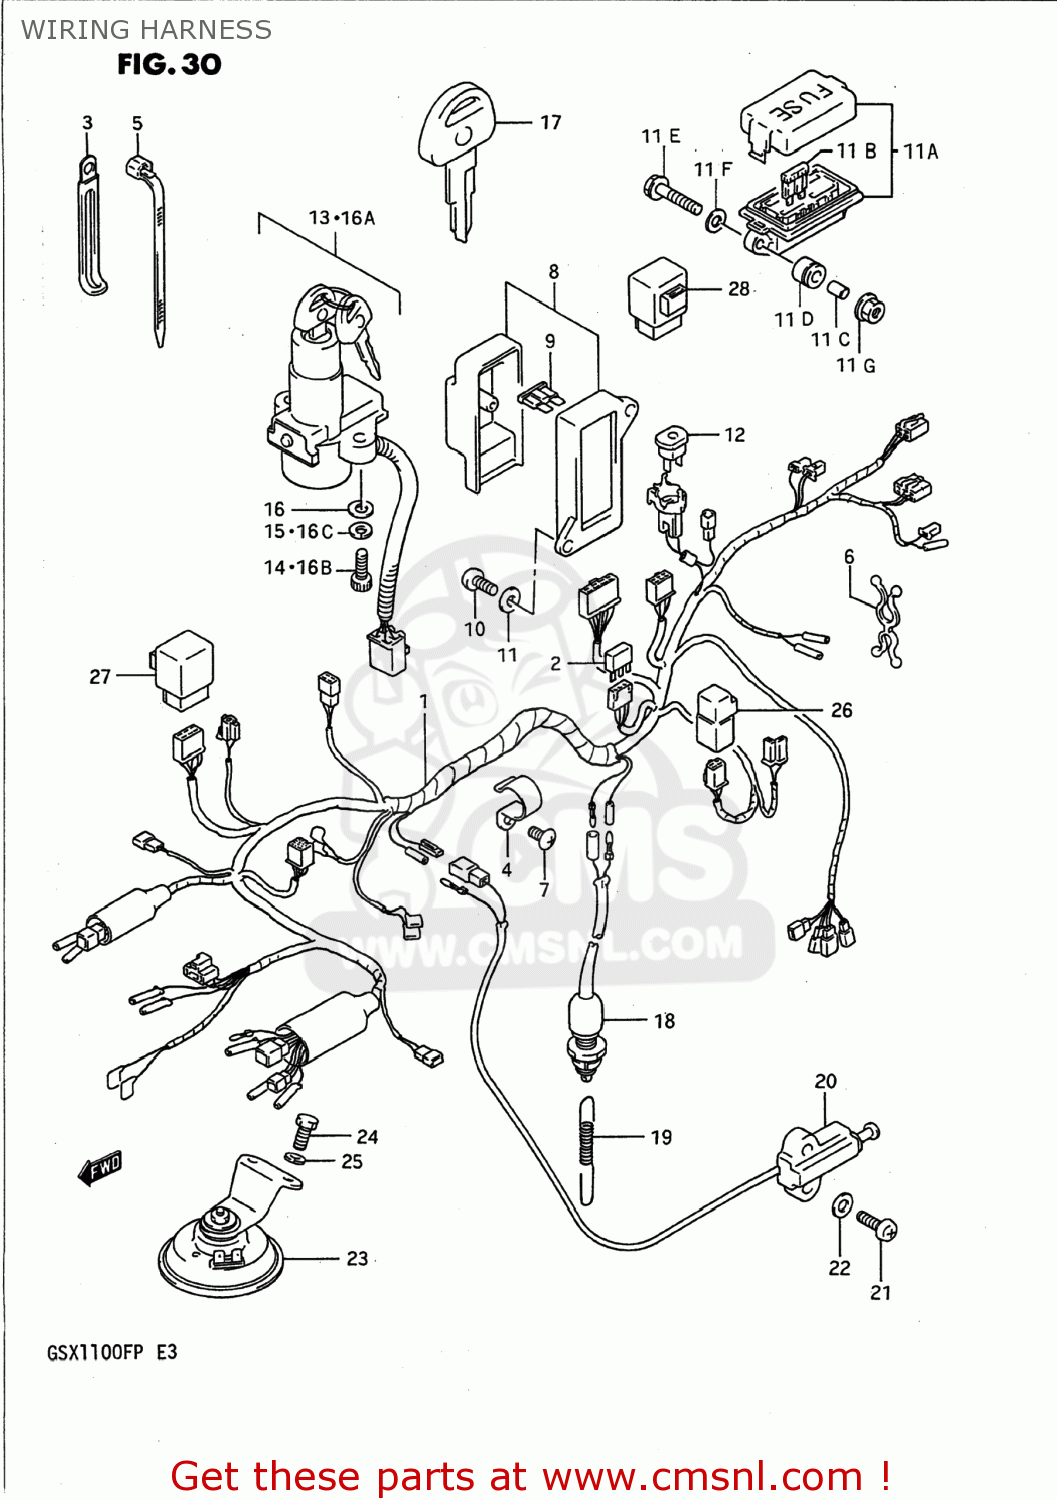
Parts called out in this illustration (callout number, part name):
1	HARNESS,WIRING
2	DIODE(STANLEY DE8804)
3	CLAMP
4	CLAMP
5	CLAMP(L:125)
6	CLAMP
7	SCREW
8	BOX ASSEMBLY,FUSE
9	FUSE(10A)
10	SCREW
11	WASHER, LOWER
11A	BOX ASSY,FUSE
11B	FUSE(10A)
11C	SPACER
11D	CUSHION 8X18X17.5
11E	BOLT
11F	WASHER(6.5X18X1)
11G	NUT
12	BREAKER ASSY,CIRCUT
13	LOCK ASSEMBLY,STEERING
14	BOLT
15	WASHER,LOCK
16	WASHER
16A	LOCK ASSY,STEERING
16B	BOLT
16C	WASHER,LOCK
17	KEY,BLANK
18	SWITCH ASSY,STOP LAMP
19	SPRING
20	SWITCH ASSEMBLY,SIDE STAND
21	SCREW
22	WASHER
23	HORN ASSEMBLY
24	BOLT
25	WASHER,LOCK
26	RELAY ASSEMBLY
27	RELAY ASSY,MOTOR CONTROL
28	CONTROLLER ASSY,FAN MOTOR
